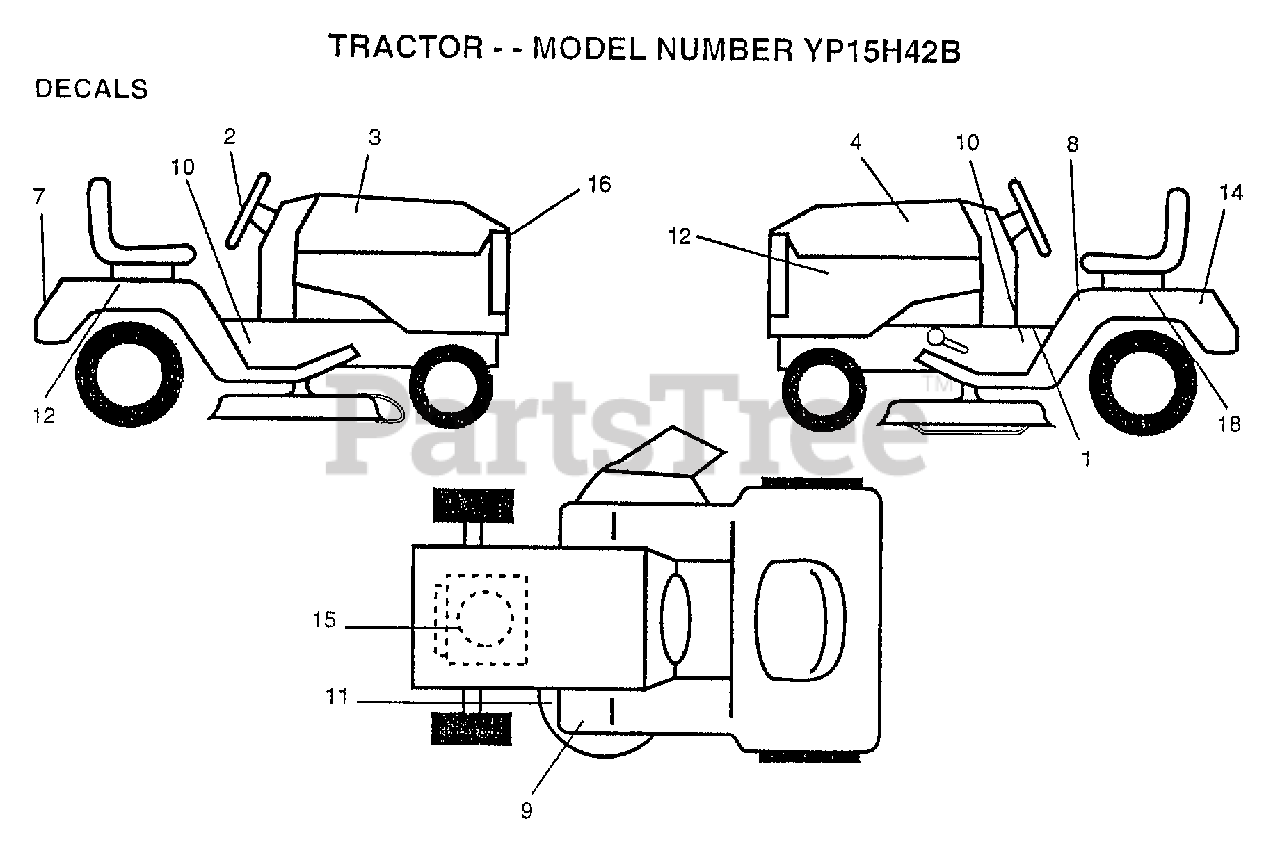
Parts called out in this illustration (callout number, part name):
1	"DECAL INST,SADDLE"
2	DECAL INS STRG WH
3	"DECAL HOOD,RH"
4	"DECAL HOOD,LH"
7	DECAL FENDER
8	"DECAL DANGER,FEND"
10	DECAL CHASSIS
11	DECAL
14	DECAL.BATRY.3-3908
17	DECAL FENDER RH
18	DECAL FENDER LH
